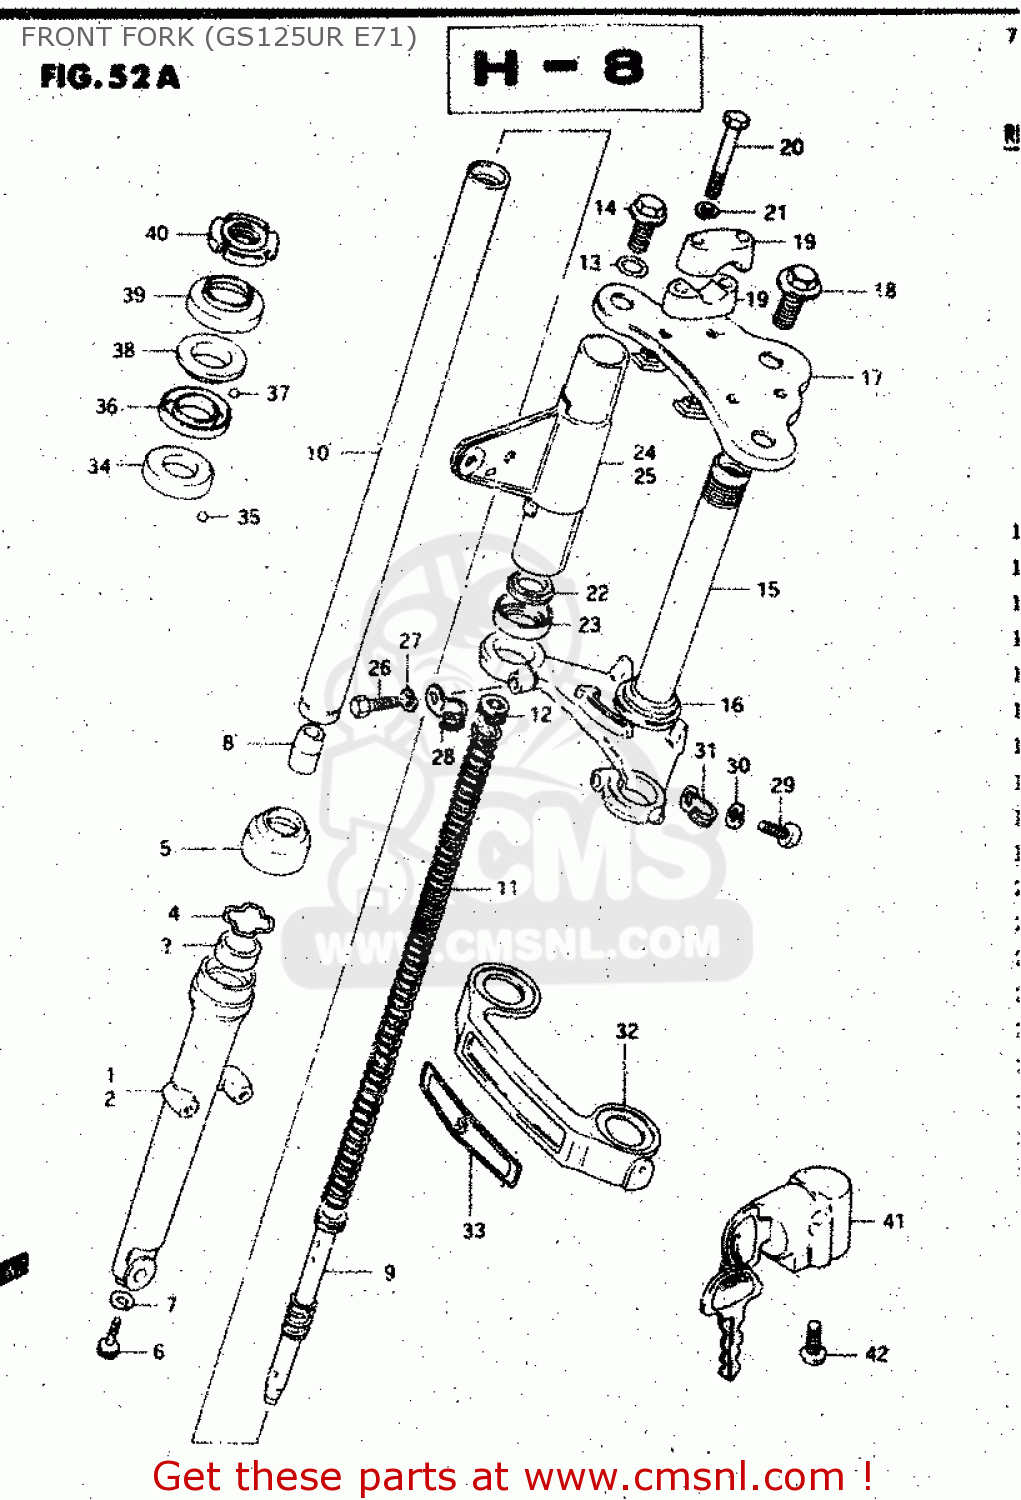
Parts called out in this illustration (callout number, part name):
1	TUBE,OUTER,R
2	TUBE,OUTER,L
3	OIL SEAL,FRONT FORK
4	RING,SNAP
5	SEAL,DUST
6	BOLT,FORK CYLINDER(10X25)
7	GASKET (NAS)
8	PIECE,OIL LOCK
9	FRONT FORK DAMPER TUBE
10	TUBE,FORK INNER
11	SPRING
12	NUT
13	O RING(D:2.4,ID:21.8)
14	CAP,FORK
15	STEM,STEERING
16	RACE,STEERING OUTER LWR
17	HEAD,STEERING STEM
18	BOLT
19	HOLDER,HANDLE UPR
20	BOLT
21	WASHER,LOCK
22	CUSHION,HEAD LAMP BRACKET
23	GUIDE,BRACKET
24	BRACKET,HEADLAMP,R
25	BRACKET,HEADLAMP,L
26	BOLT,FR FORK LWR(12X33)
27	WASHER,LOCK
28	CLIP
29	SCREW
30	WASHER,LOCK
31	CLIP,BRAKE CABLE
32	COVER,FR FORK
33	EMBLEM,FR FORK COVER
34	LACE,STEERING INNER LWR
35	BALL
36	RACE,STEERING INNER UPR
37	BALL
38	RACE,STEERING OUTER UPR
39	DUST SEAL,STEERING UPR
40	NUT,STEERING STEM(25X44X10)
41	LOCK ASSY,STEERING
42	SCREW
